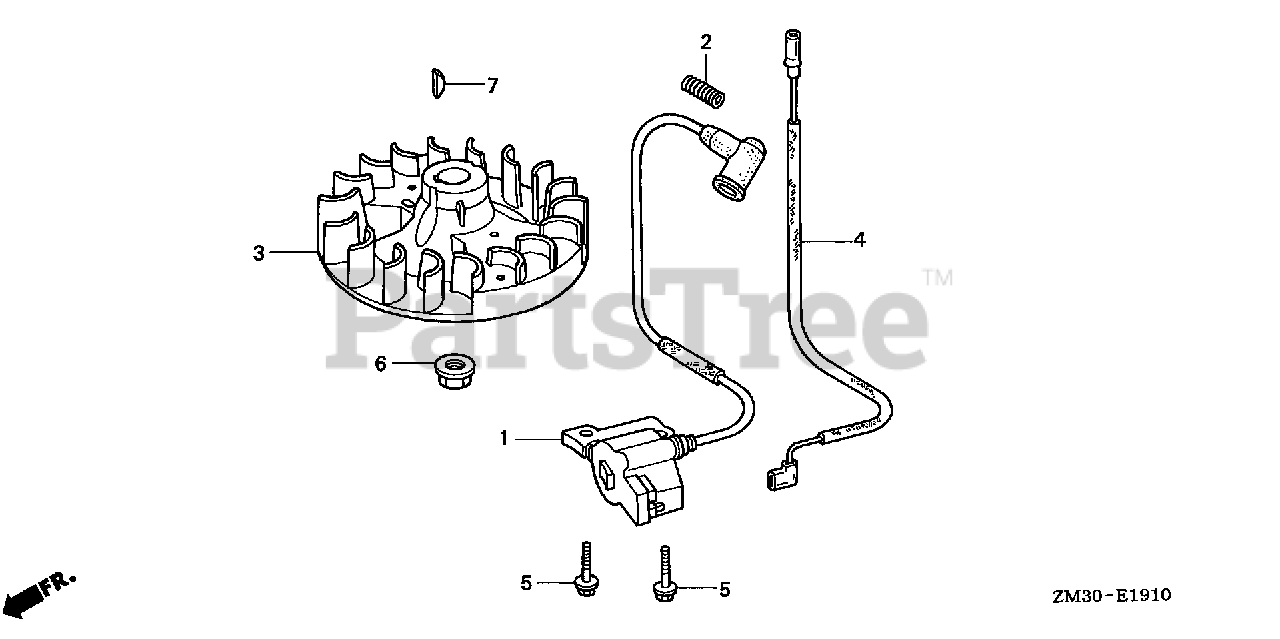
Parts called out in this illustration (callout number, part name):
1	COIL ASSY., IGNITION
2	TUBE A, CORRUGATED (7X18)
4	WIRE, STOP SWITCH
5	BOLT-WASHER (5X16)
6	NUT, FLANGE (10MM)
7	KEY, WOODRUFF (16X12)
